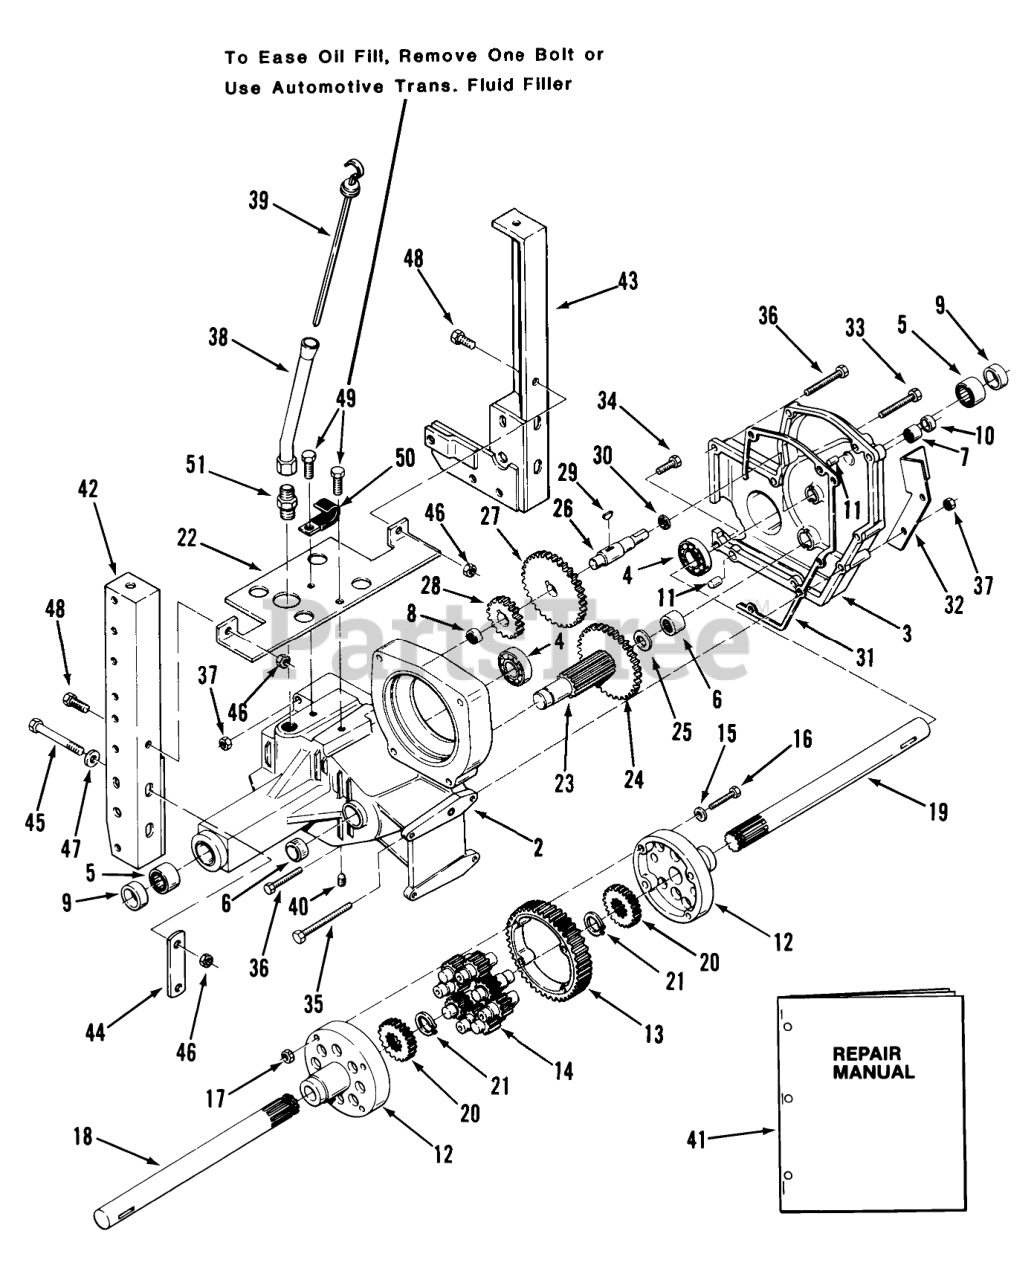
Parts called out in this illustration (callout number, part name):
2	TRANS CASE RH
3	Case-Transaxle LH
4	BALL BRG 1 1/2 I.D.
5	BEARING
6	BEARING-NEEDLE
7	NEEDLE BEARING
8	BEARING-NEEDLE
9	SEAL-OIL
10	Seal
11	PIN-LOCATING
12	DIFFERENTIAL END CAP
13	GEAR-DIFFERENTIAL RING, 43T
14	Hydro-Gear Unit (Rebuilt)
15	WASHER
16	BOLT-HEX
18	Rear Axle RH-Long (15 7/8 in.)
19	Rear Axle LH-Short (12 7/8 in.)
20	GEAR-AXLE DIFFERENTIAL
21	RING-SNAP
22	Rear Plate
23	PINION SHAFT
24	GEAR 46T
25	WASHER-THRUST
26	SHAFT GEAR
27	GEAR 46 TEETH
28	GEAR 20 TEETH
29	Key
30	Race Thrust
31	GASKET-TRANSMISSION
32	BRACKET-BRAKEB
33	Bolt
34	Bolt
35	H H C S
36	Screw-Hex. Hd.
37	Nut
38	Filler Tube
39	Dipstick
40	PLUG 1/4 PIPE ALLEN
41	Repair Manual
42	Hitch Support Bracket RH
43	Hitch Support Bracket LH
44	BRACKET-REAR LINK MOUNTING
45	BOLT-HEX
46	NUT
47	Washer
48	BOLT
49	BOLT
50	CLIP
51	Fitting
